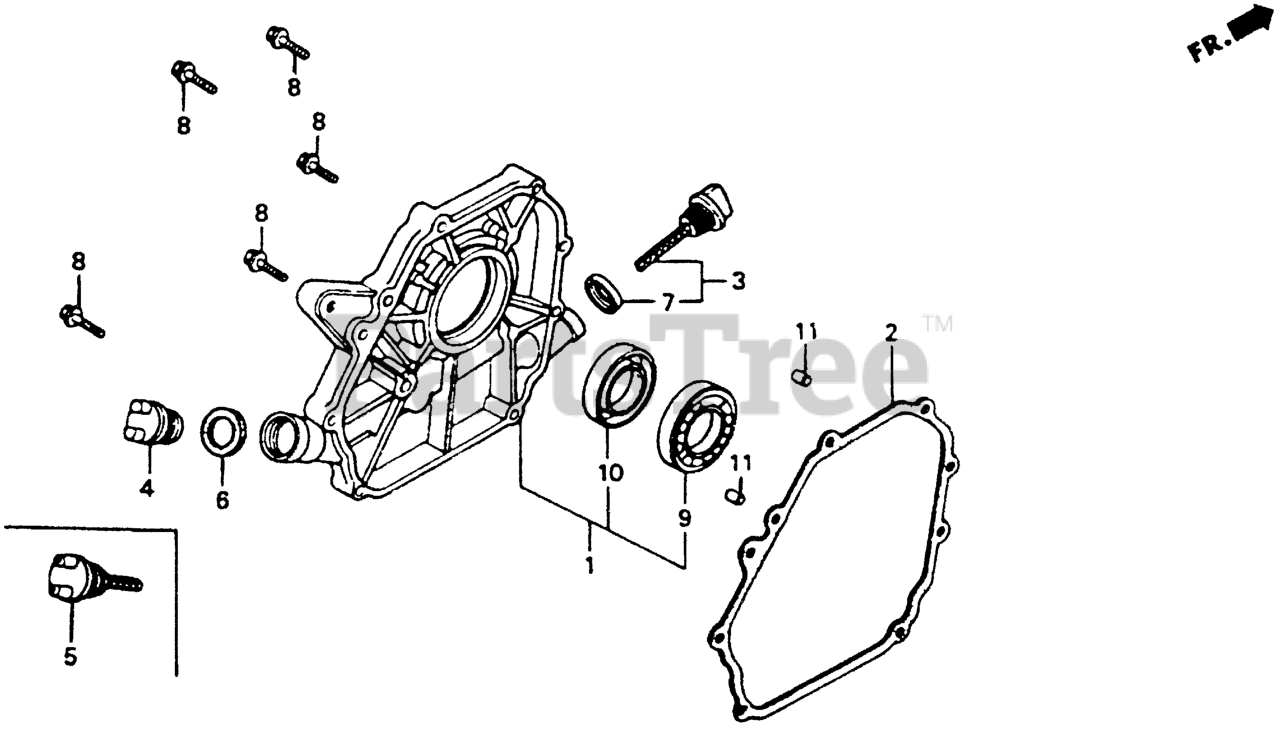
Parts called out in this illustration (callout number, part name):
1	COVER ASSY., CRANKCASE (W-TYPE)
1	COVER ASSY., CRANKCASE
2	GASKET, CASE COVER (NON-ASBESTOS)
3	CAP ASSY., OIL FILLER
4	CAP, OIL FILLER
5	CAP, OIL HOLE
6	GASKET, OIL FILLER CAP Use from Engine SN 1391010.
7	GASKET, OIL FILLER CAP
8	BOLT, FLANGE (8X32)
9	BEARING, RADIAL BALL (6205)
10	OIL SEAL (25X41X6)
11	PIN A, DOWEL (8X14)
